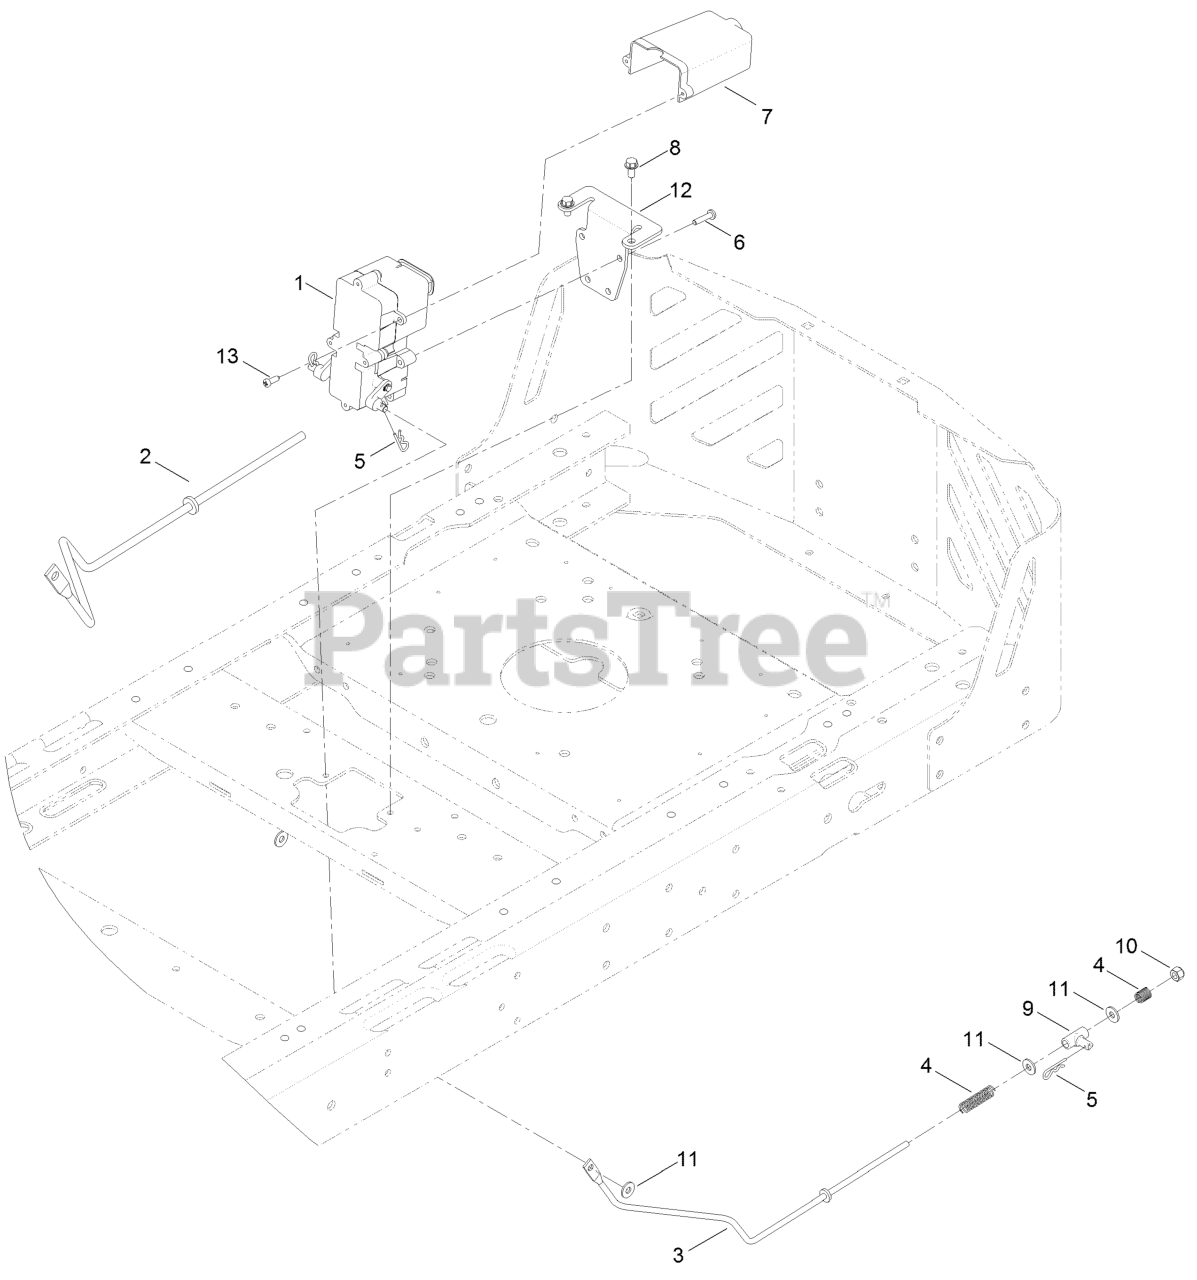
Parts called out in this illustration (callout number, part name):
2	ROD-BRAKE, RH
3	ROD-BRAKE, LH
4	SPRING-COMPRESSION
6	SCREW-PPH
8	SCREW-HWH
9	MOUNT-PIVOT
10	NUT-LOCK, NI
12	BRACKET-MOUNT, BRAKE
13	SCREW-PPH
